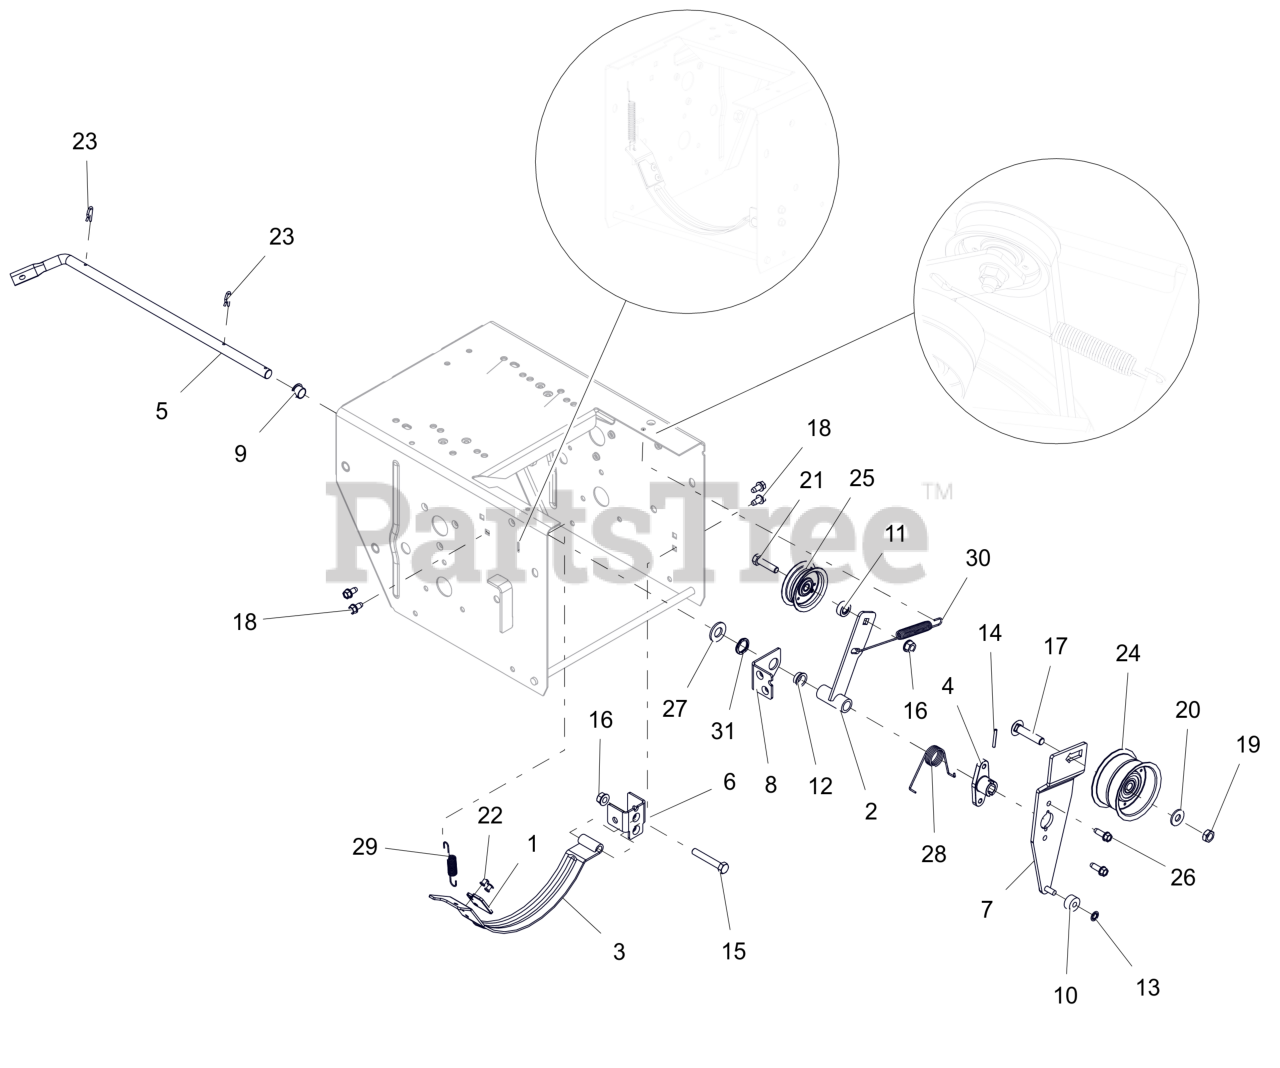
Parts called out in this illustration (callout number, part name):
1	PAD, BRAKE
2	ARM, IDLER -TRACTION
3	ARM, BRAKE-ATTACHMENT
4	HUB, BRAKE ARM
5	ARM, ATTACHMENT
6	PIVOT, BRAKE
7	ARM, IDLER - ATTACHMENT
8	BRKT, SUPPORT
9	BUSHING, POLYLINER-.50 SPLIT
10	BSHG,SLV .265 X .625 X .375
11	SPCR, BRG .315X.500X.358X.281
12	BSHG,FLANGE .500X.625X.270X.75
13	RG-RTNG-EXT .250X.010
14	PIN-ROLL .125X1.00
15	BLT, HEX .31-18X2.00 G5 ZCC
16	NUT-LK-TOP-FLG .312-18 GF ZCC
17	BLT, RHSSN .38-16X1.75 G5 ZCC
18	SCR-TAP .25-20X.50 HWH ZCC
19	NUT-LK-CTR-JAM .375-16 GB ZCC
20	WSHR,FLT .375X.875X.083 ZCC
21	BLT, HEX .31-18X1.25 G5 ZCC
22	RVT, POP .1875 ZCC
23	CLIP, SPRING
24	IDLER, FLANGE -2.75 OD X .375 ID
25	IDLER, FLAT - 2.00"
26	SCR,TAP .25-20X.75 HWH TR ZCC
27	WSHR,FLT .531X1.062X.095 ZCC
28	SG-TORS .067X.88
29	SPRING-EXT .437 X .438 X 2.64
30	SG-TENS .06X.482X5.35
31	WAVE SPRING .600X.875X.25FH
